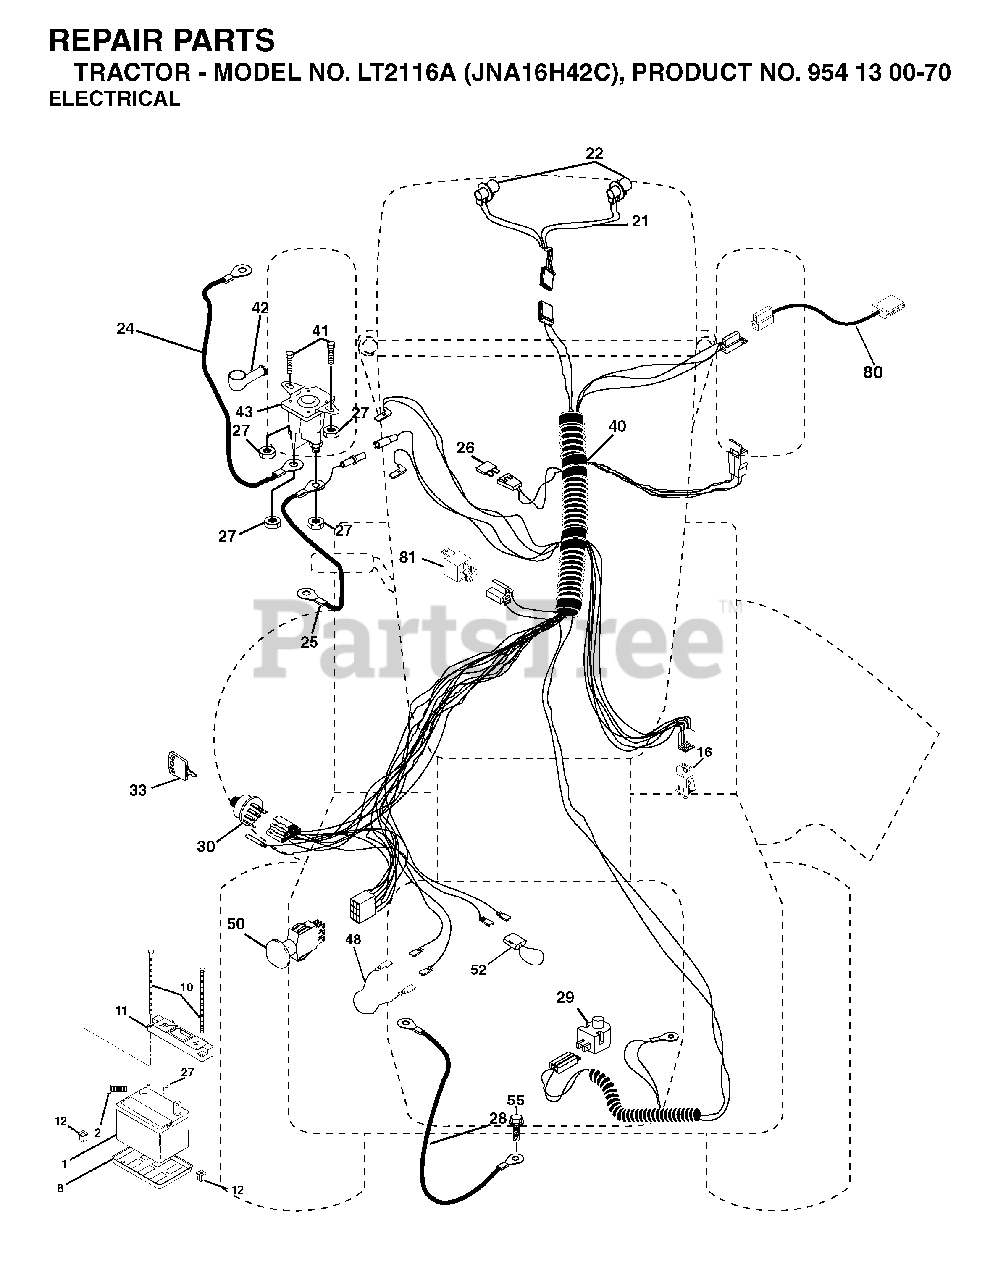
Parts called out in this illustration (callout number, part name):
1	REPL BY 532 12 38-99
8	BATTERY TRAY T
10	BOLT 1/4-20 X 7.5
11	BATTERY HOLDDOWN
12	NUT, PUSH NYLON 1/4" BATTERY
16	SWITCH INTERLOOK PUSH-IN
21	WIRE HARNESS
22	LIGHTBULB
24	BATTERY CABLE GT
25	CABLE BATTERY 6 GA 22" W/16W
26	FUSE 20AMP
27	NUT
28	CABLE GROUND 6 GA 21" 90T BLK
29	PLUNGER SWITCH (COLOR:OLIVE)
30	IGNITION SWITCH
33	KEY MLD GEN DELTA
40	HARNESS IGN.
42	TERMINAL COVER
43	SOLENOID
50	PTO SWITCH
52	WIRE PROTECTION LOOP
55	SCREW LT
80	HARNESS, CLUTCH
81	RELAY.ASSY.T
